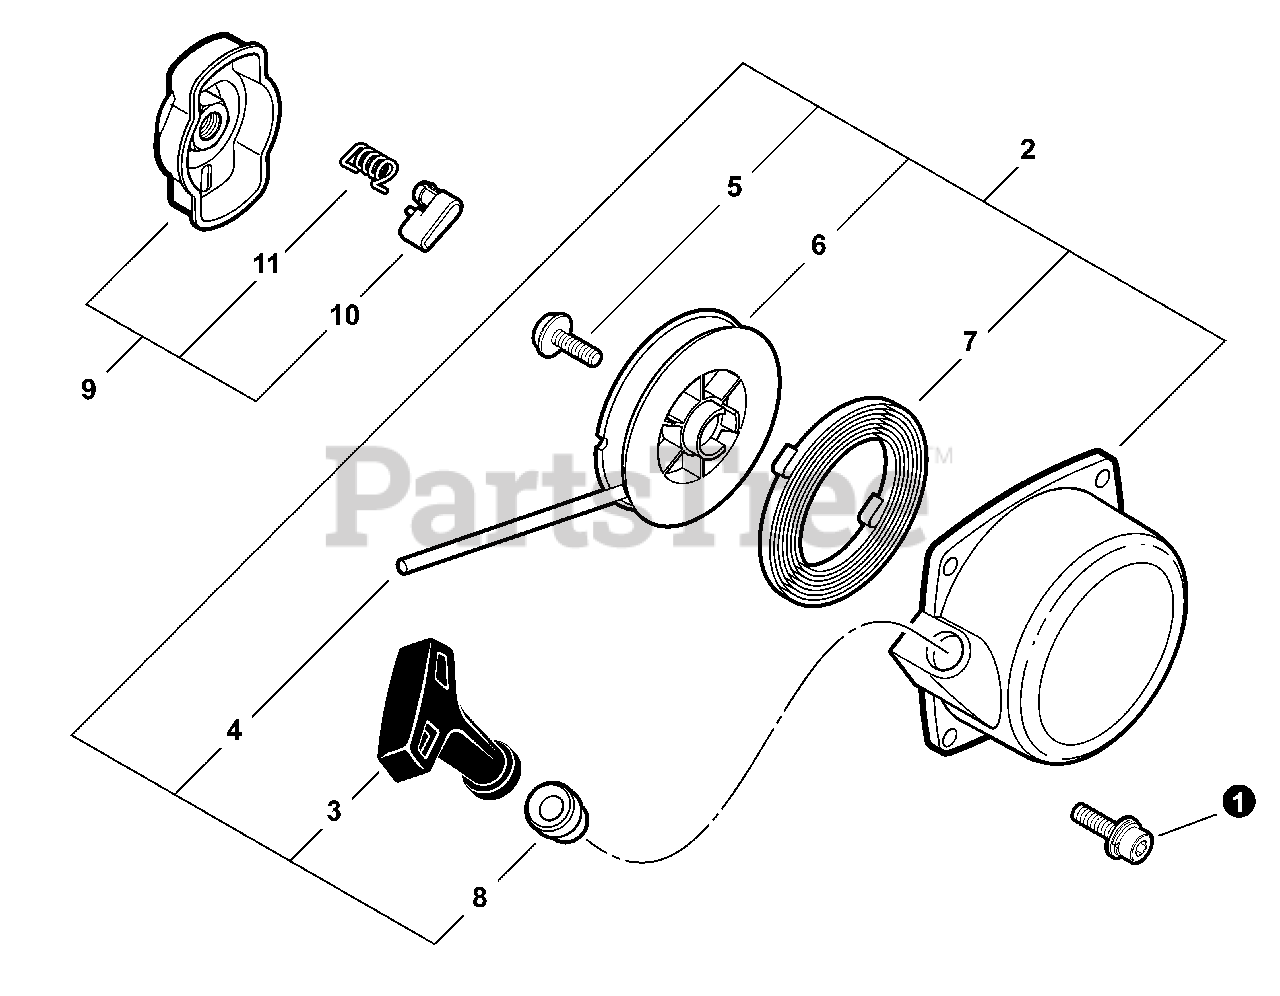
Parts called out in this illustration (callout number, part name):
1	BOLT 4×16
2	STARTER ASSY, RECOIL
3	GRIP, STARTER
4	ROPE, STARTER 3.0×1000
5	SCREW
6	REEL, ROPE
7	SPRING, RECOIL
8	GUIDE, ROPE
9	PAWL ASSY, STARTER
10	PAWL, STARTER - BLACK
11	SPRING, RETURN
